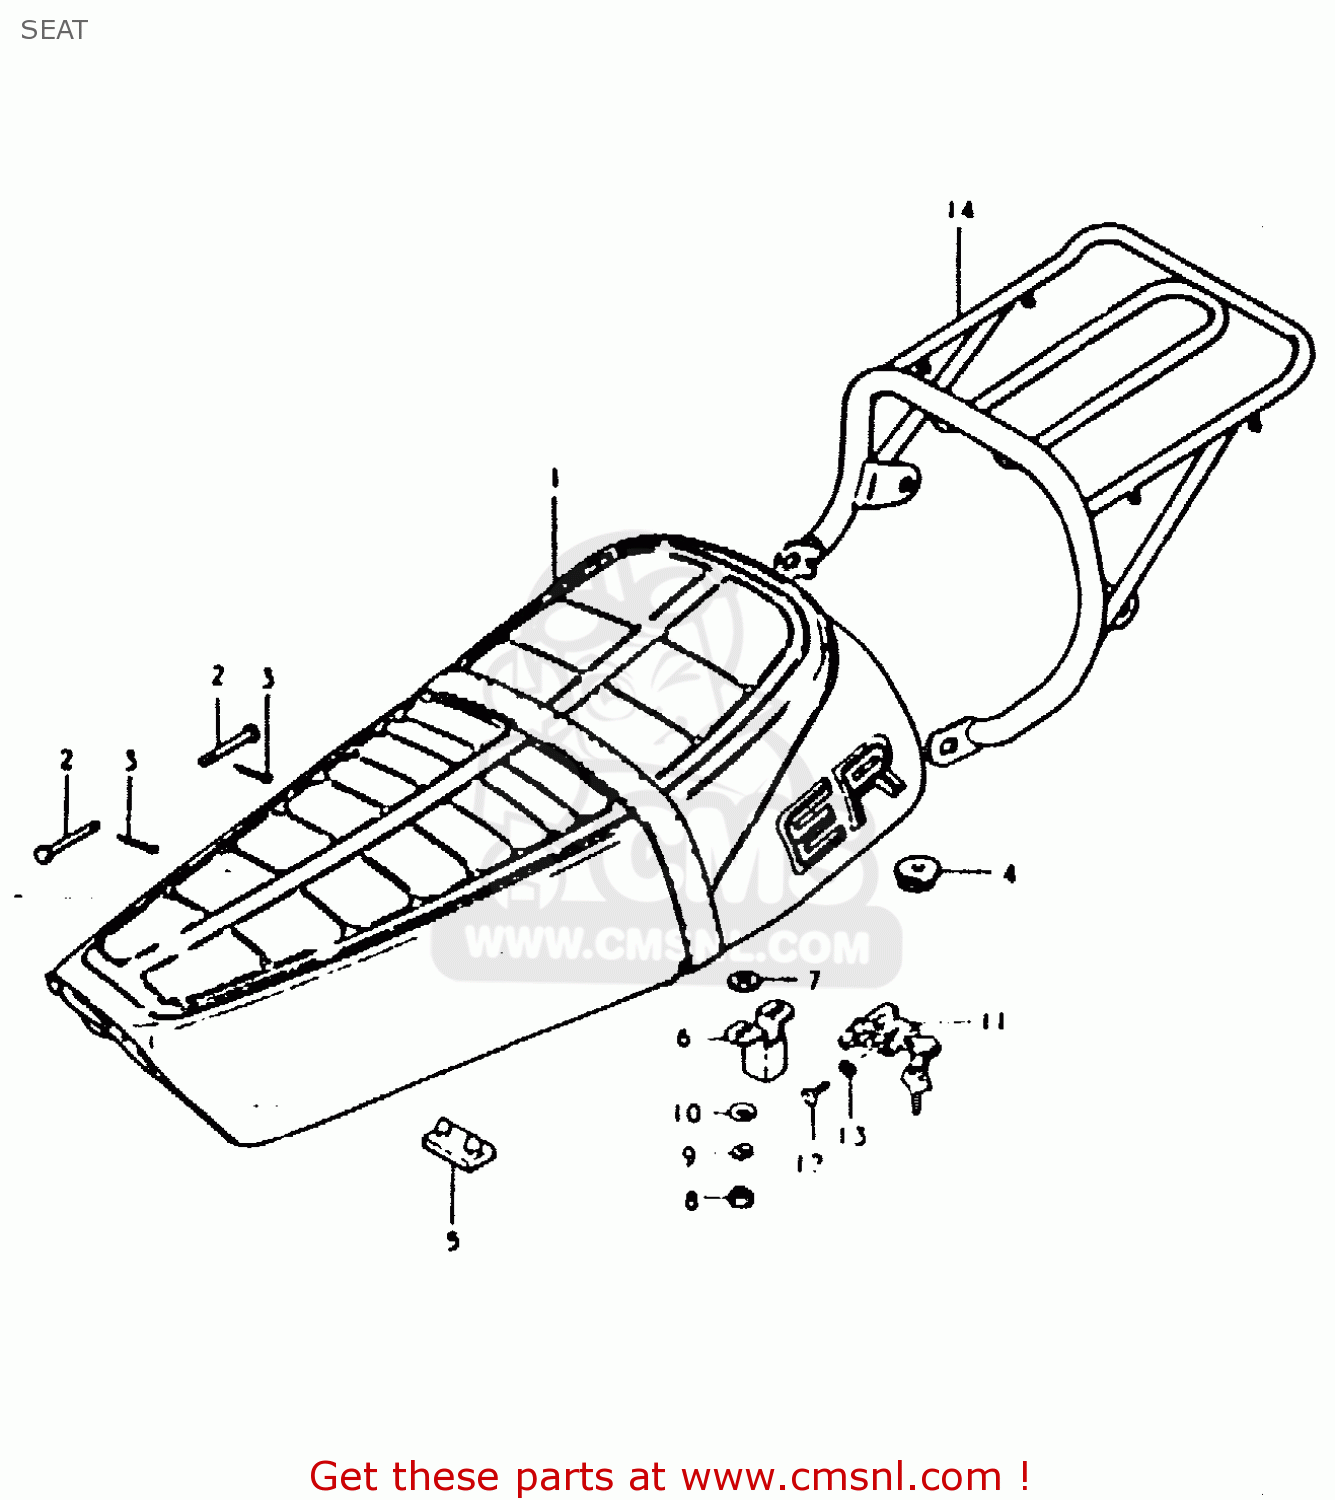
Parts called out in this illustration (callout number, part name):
1	SEAT ASSY (BLACK)
2	PIN
3	PIN
4	CUSHION
5	CUSHION
6	PLATE,CLAMP GUIDE
7	WASHER(8.5X18X1)
8	NUT
9	LOCK WASHER
10	WASHER
11	LOCK ASSY,SEAT
12	SCREW
13	LOCK WASHER
14	CARRIER,SPORT
